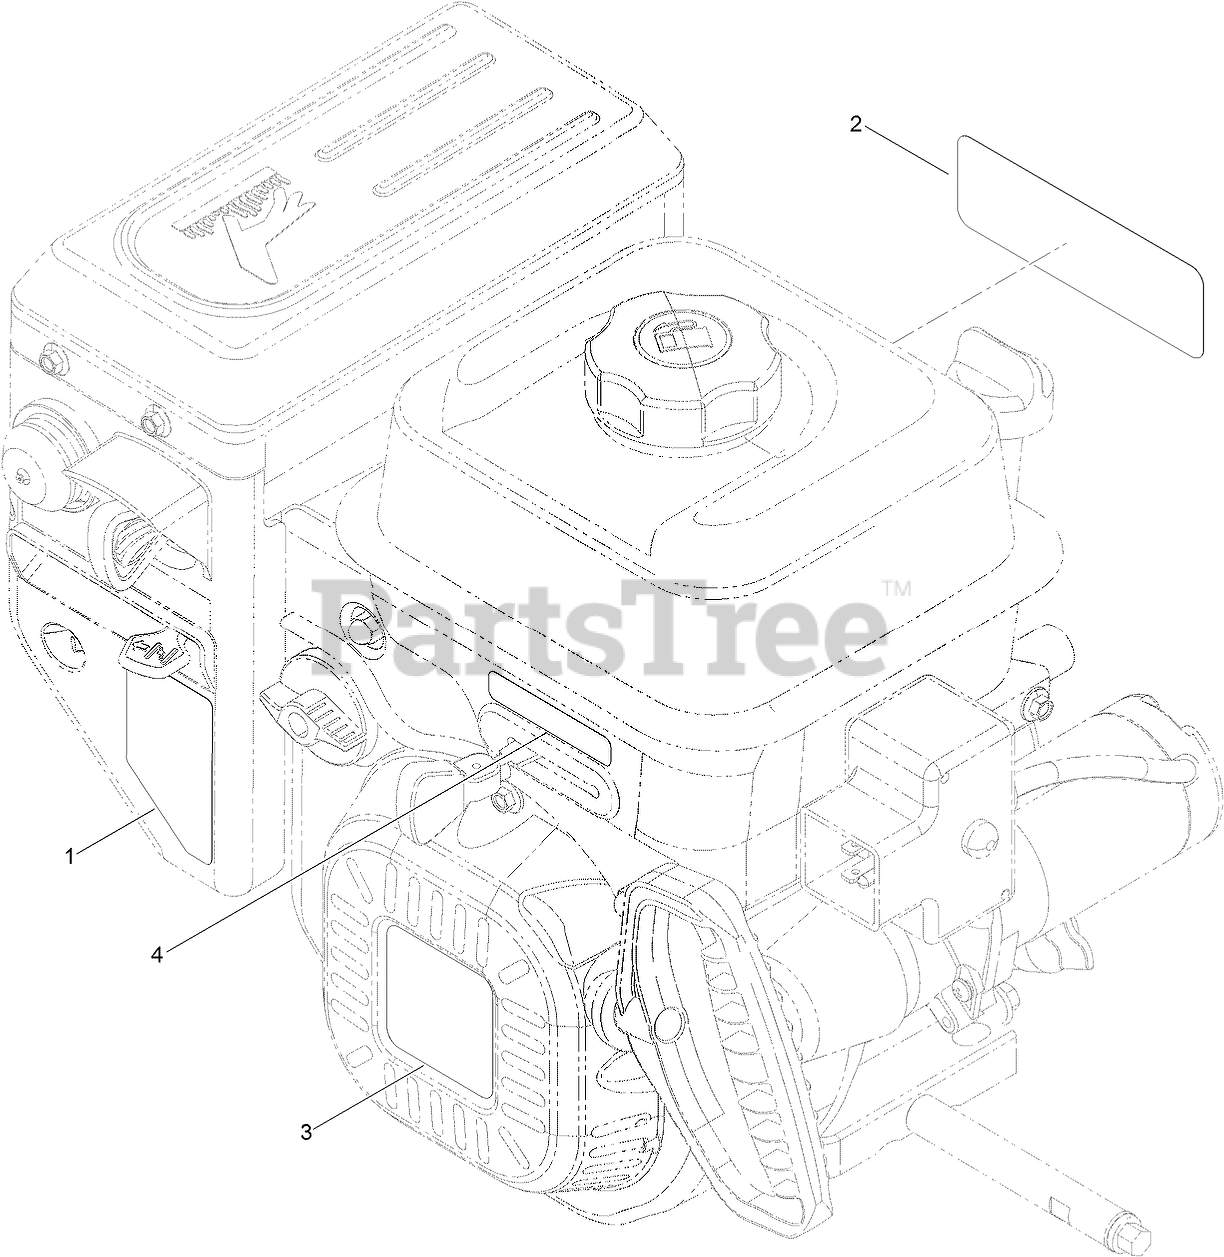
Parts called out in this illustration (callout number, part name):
1	DECAL-CONTROL, ENGINE
2	DECAL-ENGINE, SERIES G210
3	DECAL-RECOIL, G210
4	DECAL-THROTTLE
